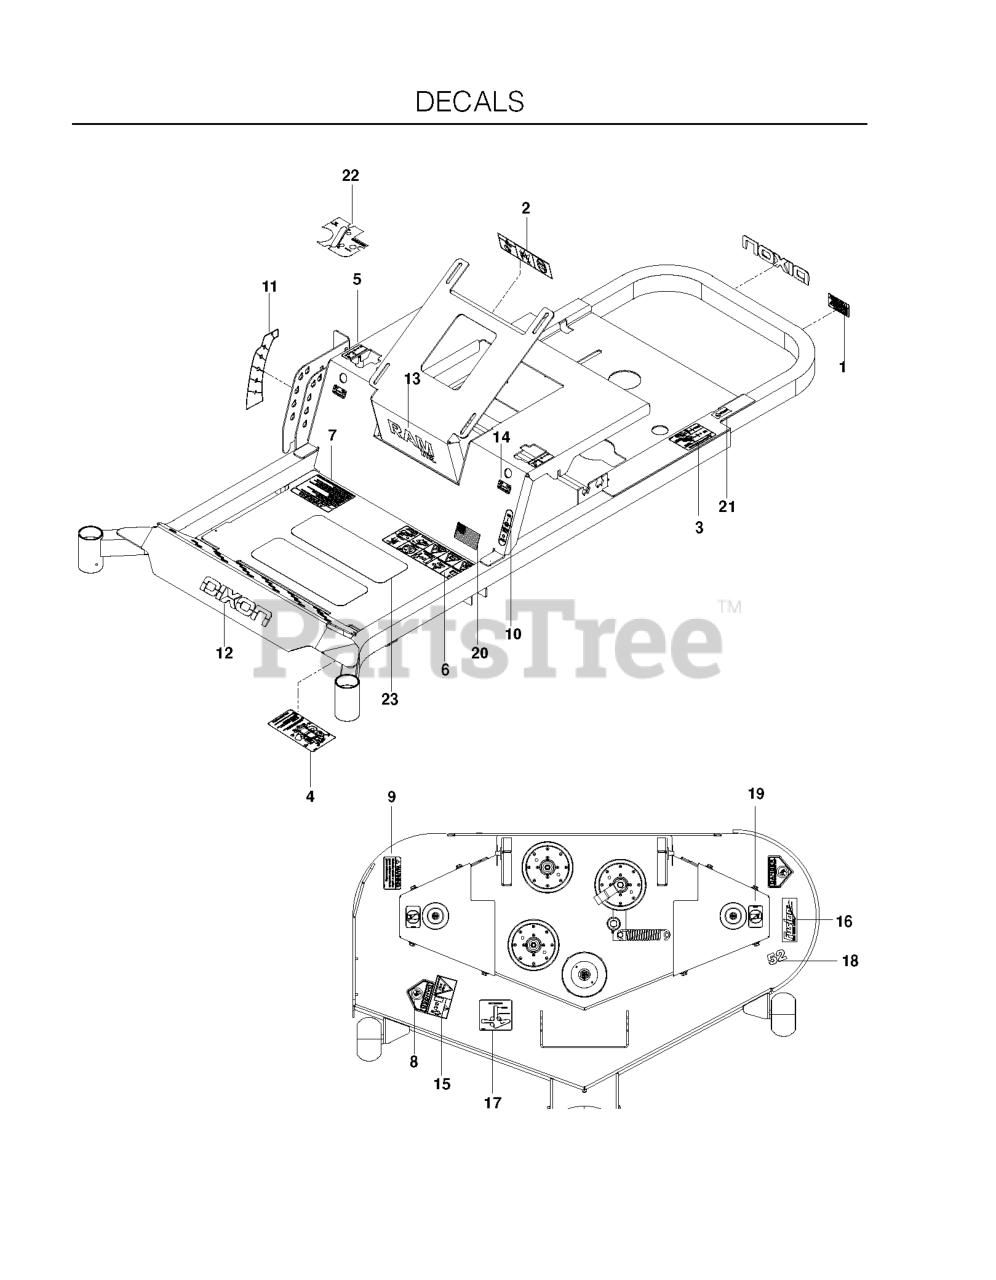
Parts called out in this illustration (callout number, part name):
1	DECAL, PROP. 65
3	DECAL, DO NOT MOUNT
4	DECAL, SERVICE
5	DECAL, MOTION CONTROL
6	DECAL, SAFETY WARNING
7	DECAL, WARNING
8	DECAL, CPSC
9	DECAL, CAUTION
10	DECAL, PARK BRAKE
11	DECAL, HEIGHT
12	DECAL, DIXON
13	DECAL, RAM ZTR, 2008
14	DECAL, TRACKING
15	DECAL, EURO SEVERING
16	DECAL, FUSION
17	DECAL, BELT ROUTING
19	DECAL, NO STEP
20	DECAL, FLAG
21	DECAL, ECM, AUSTRALIA
22	DECAL, CONTROLS PANEL, DIX
23	ANTI-SKID PAD
